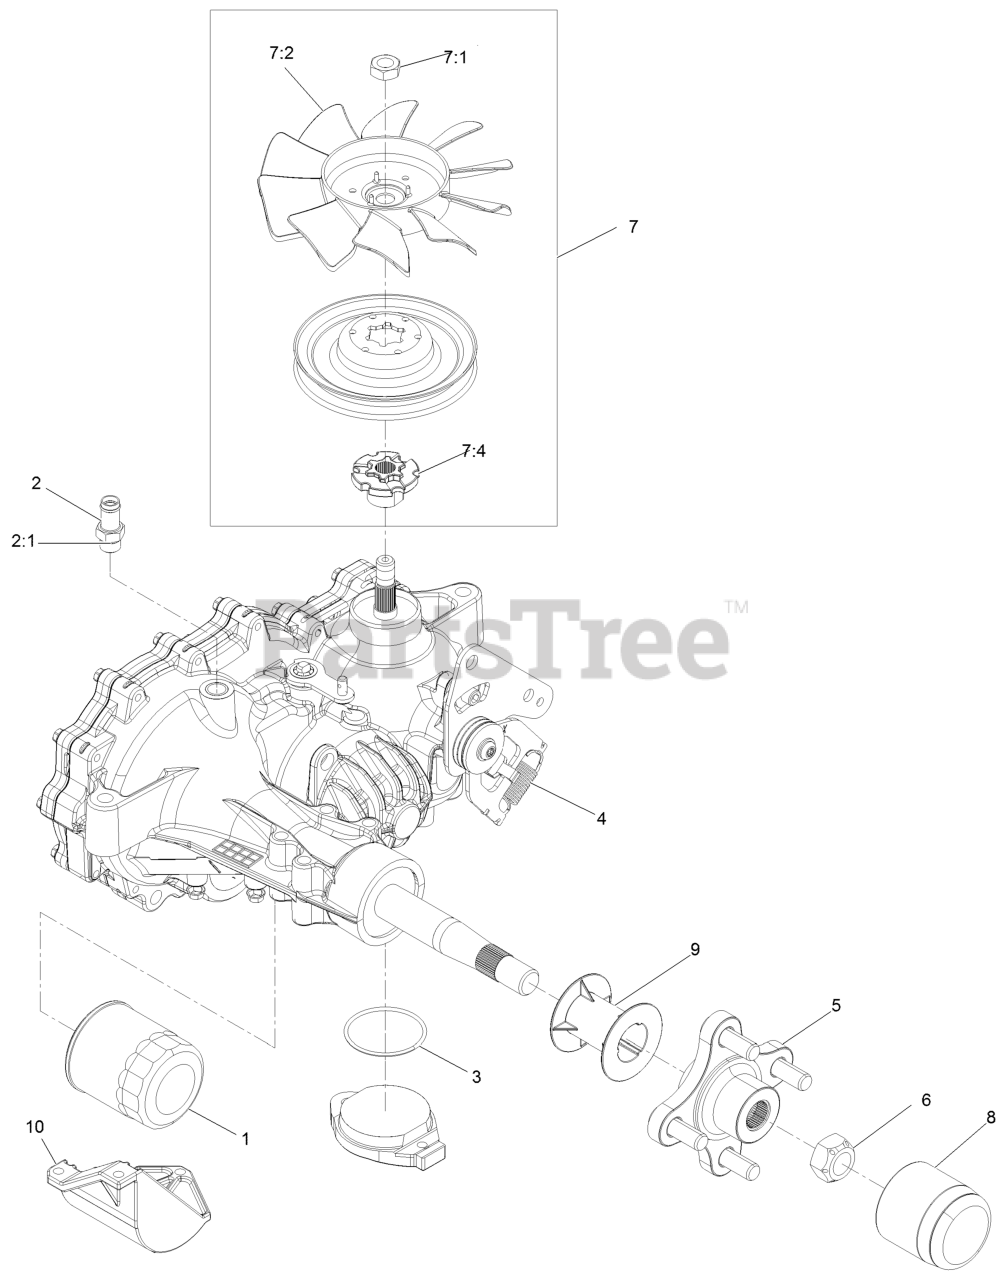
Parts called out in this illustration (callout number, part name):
1	ELEMENT-OIL FILTER, HYD
2	ADAPTER-STRAIGHT
2:1	O-RING
3	O RING-SEAL
4	SPRING-EXTENSION
5	HUB-OFFSET
6	NUT-HUB
7	FAN AND PULLEY KIT
7:4	HUB-PULLEY
8	CAP-AXLE, LONG
9	TUBE-AXLE
10	GUARD-FILTER, RH
